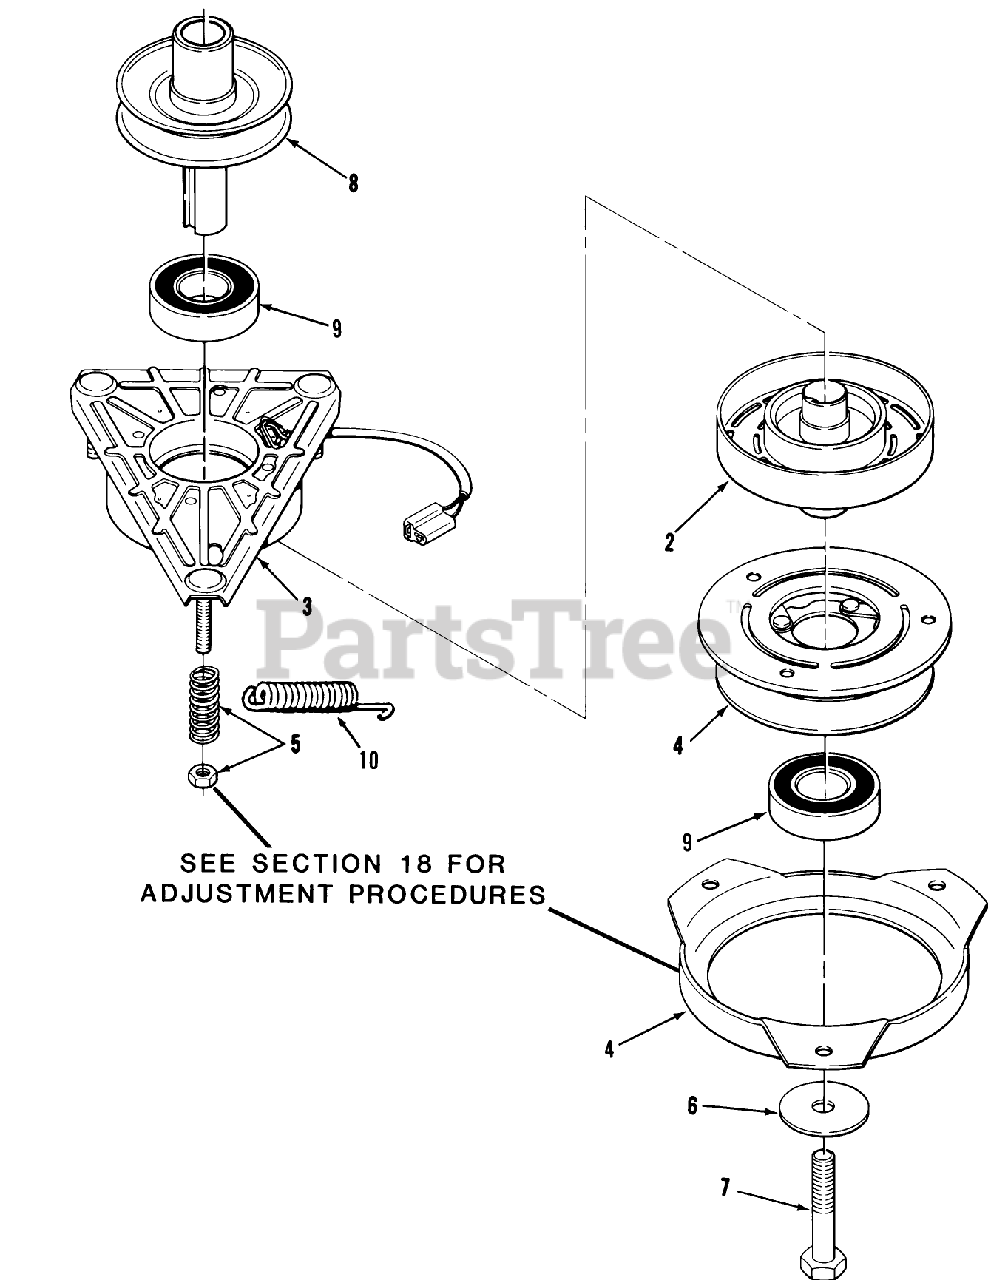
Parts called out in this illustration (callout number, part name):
5	ACCESS SPRING & NUT
6	WASHER
9	BEARING-ELEC CLUTCH
